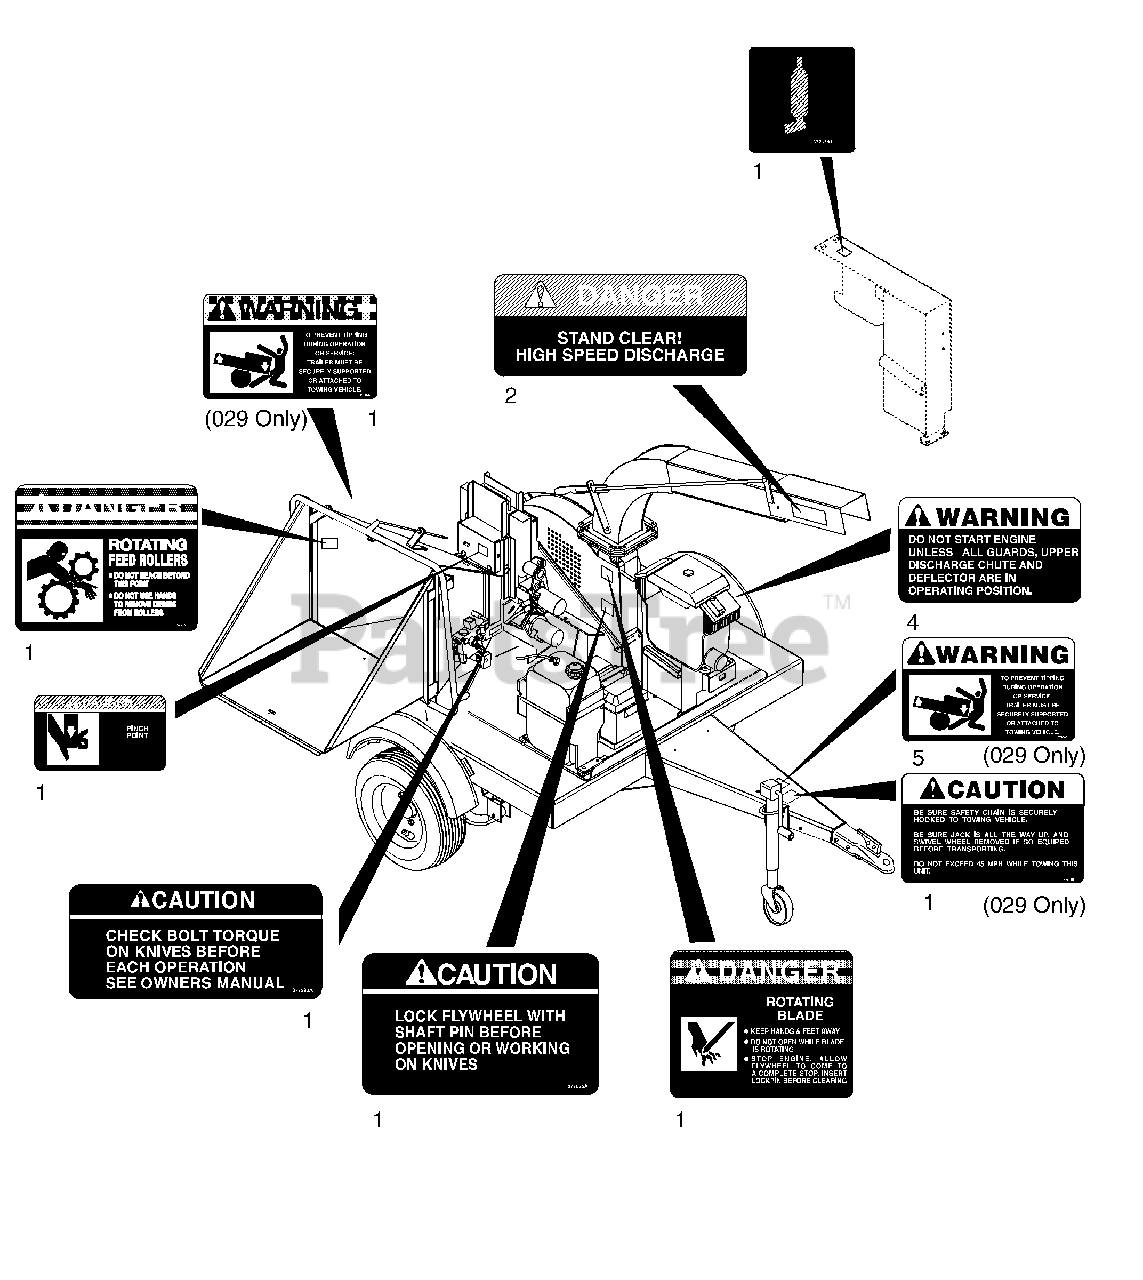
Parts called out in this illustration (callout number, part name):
1	Decal Set
2	Decal Set Large Chipper
4	Decal - Warning, Start Engine
5	Decal - Warning, Start Tipping
